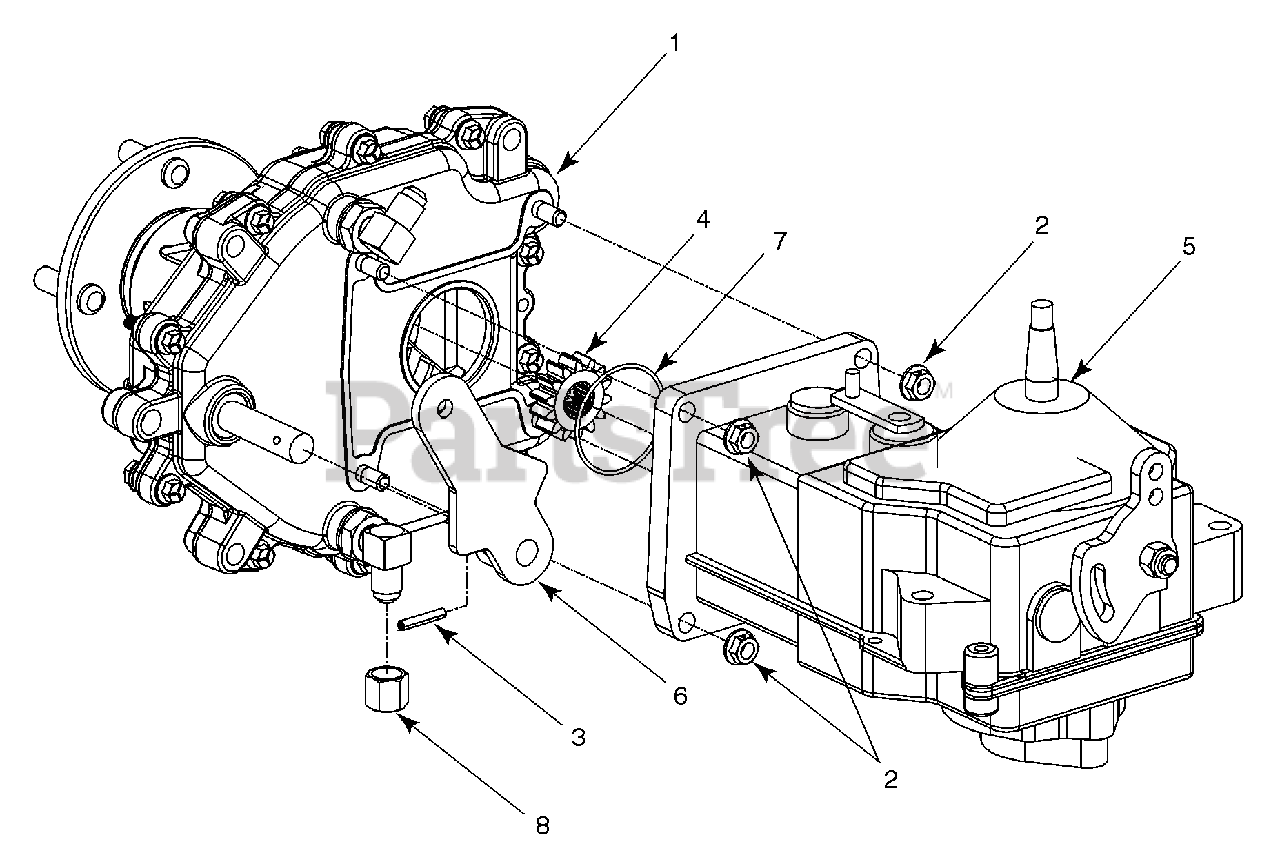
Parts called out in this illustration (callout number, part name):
1	Drive Ass'y Complete
2	Hex Flange Lock Nut 5/16-18
3	Spirol Pin 3/16 x 1.25
4	Spur Gear 14T
5	Hydro Transmission
6	Parking Brake Lever
7	O-Ring 2.0 Dia.
8	Cap Nut 3/8
